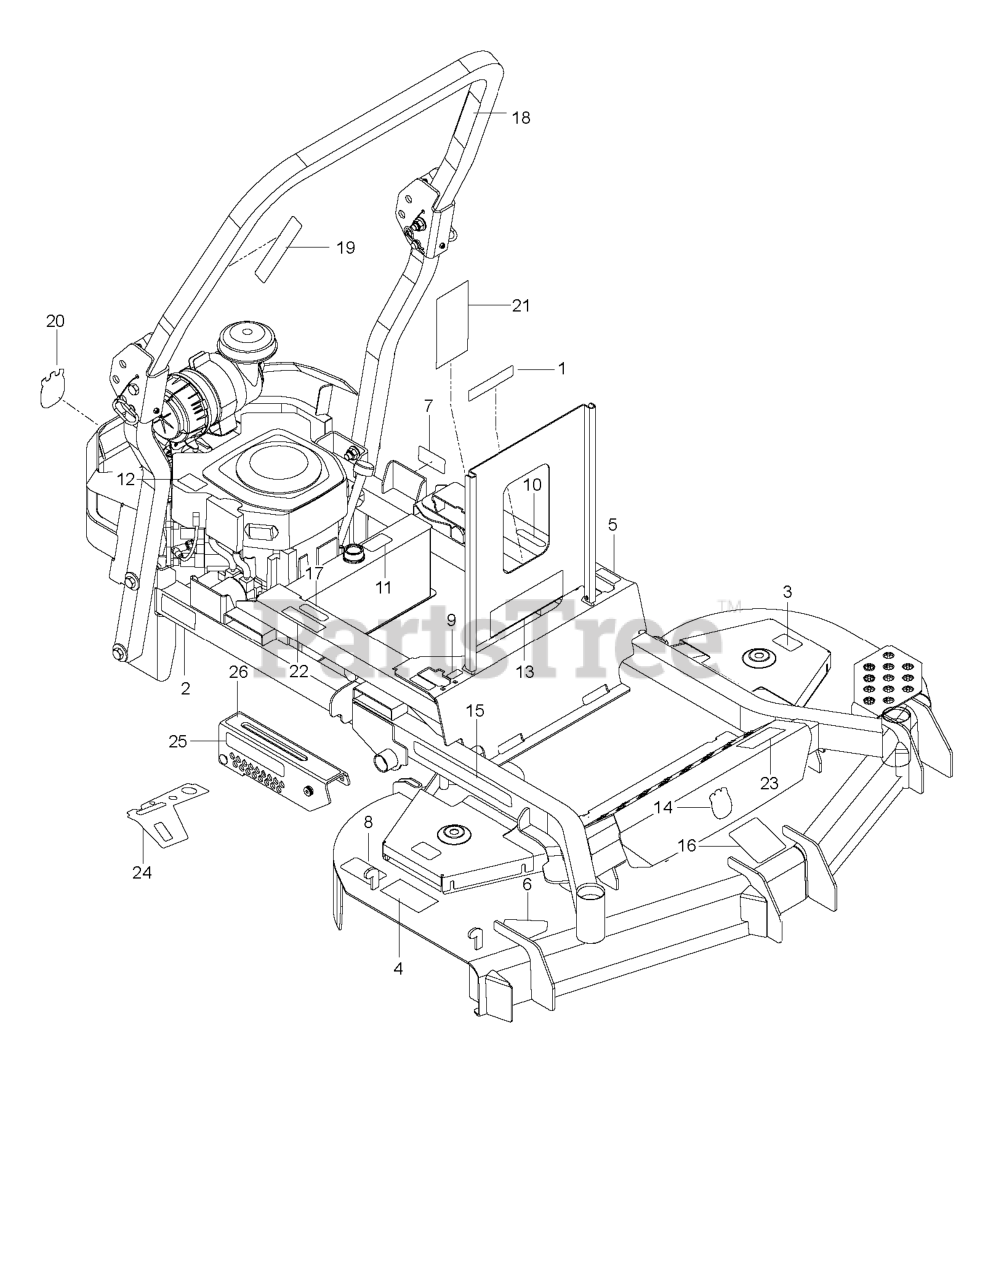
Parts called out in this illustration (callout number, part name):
1	EURO DECAL-BATTERY WARNIN6
2	DECAL, BELT DRIVE
3	DECAL, NO STEP
4	DECAL, EURO SEVERING
5	DECAL, MOTION CONTROL
6	DECAL, CPSC
7	DECAL, PROP. 65
8	DECAL, CAUTION
9	DECAL, F.S.T.
10	DECAL, PARK BRAKE
11	DECAL, OIL TANK
12	DECAL, EXHAUST
13	DECAL, WARNING
14	DECAL, CROWN H 70MM
15	DECAL.HOOD.LOGO.ORANGE.HUSQVAR
16	DECAL, BELT ROUTING
17	DECAL, FUSE
18	DECAL, ROPS
19	DECAL, ROPS, WARNING
20	DECAL, CROWN H, 110MM
21	DECAL, SERVICE
22	DECAL, WARNING SPARK ARRESTOR
23	DECAL, PZ5426
24	DECAL, CONTROL, GAS
25	DECAL, HEIGHT
26	DECAL, HEIGHT
